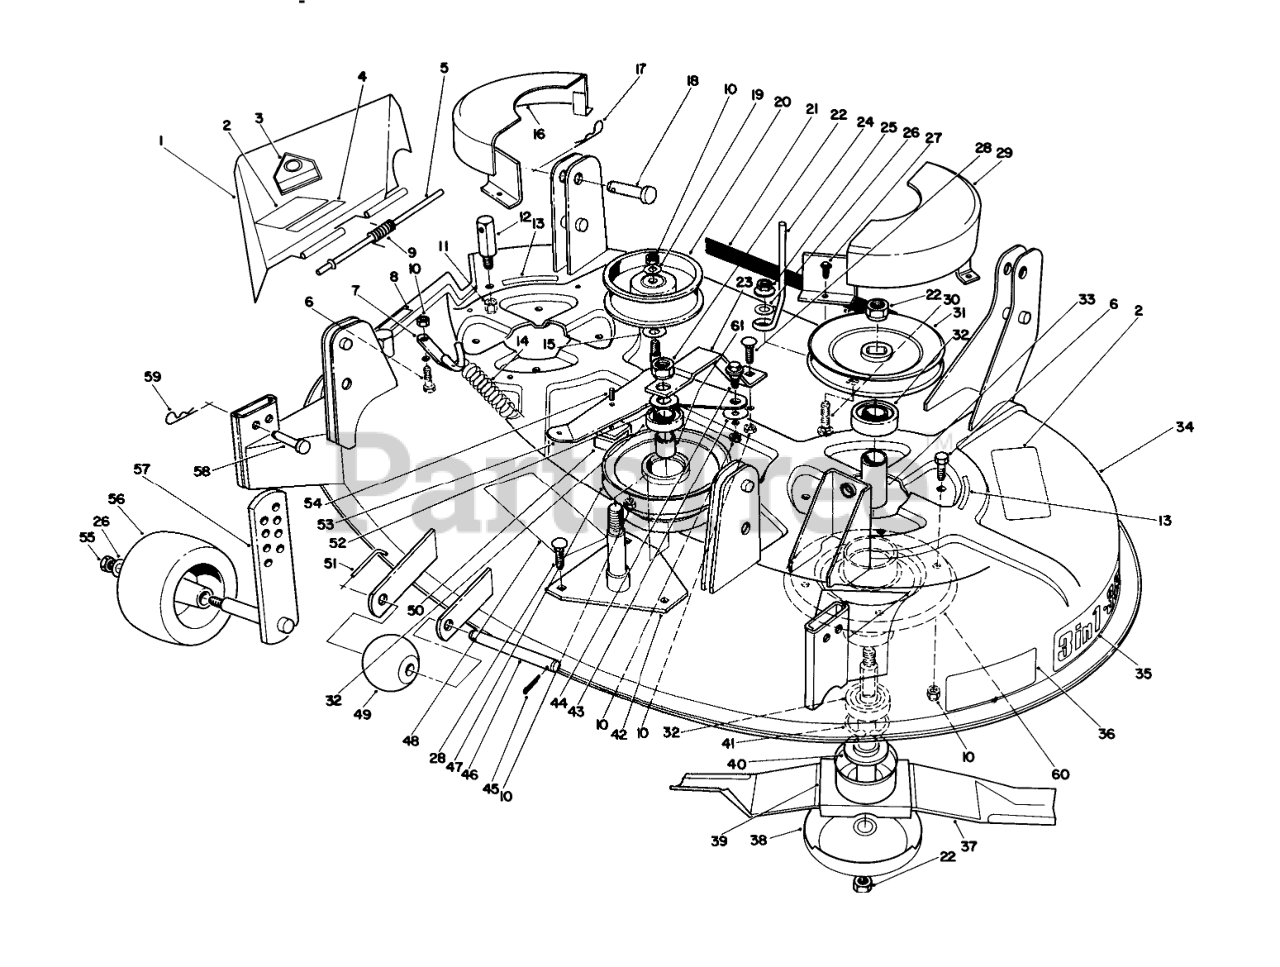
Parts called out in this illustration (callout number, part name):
1	Deflector Assembly (Incl. Ref. #2-4)
2	DECAL-DANGER, THROWN OBJECT
3	DECAL-DANGER
4	DECAL-NO STEP
5	ROD-HINGE DEFLECTOR
6	SCREW-HH
7	SPRING ROD
8	DECAL-DANGER, DEFLECTOR
9	SPRING
10	NUT-LOCK, NI
11	NUT-LOCK, NI
12	REAR PIVOT POST (PLTD)
13	DECAL-DANGER, SHIELD
14	DECK TENSION SPRNG O
15	WASHER-FLAT
16	RH BELT COVER WA B
17	PIN-HAIR
18	PIN-CLEVIS
19	WASHER-FLAT
20	PULLEY-IDLER
21	V-BELT
23	PULLEY SUPPORT B
24	BELT ROD
25	NUT-HF
26	WASHER-FLAT
27	SCREW-HWHTF
28	BOLT-CARR
29	Cover-Belt L.H.
30	SCREW-CARR
31	DECK PULLEY
32	BEARING-BALL
33	BEARING SPACER
34	Deck ) 38" (Incl. Ref. #8, 13, 35, 36 & 48)
35	DECK DECAL
36	DECAL - WHEEL ADJUSTMENT
37	Blade
38	Cup
39	SPINDLE SHAFT WA
40	IDLER SPACER
41	RING-RETAINING
42	JACK SHAFT WA B
43	WASHER-PIVOT
44	SCREW-SHOULDER
45	PIN-COTTER
46	SHAFT-ROLLER
47	PULLEY ASSEMBLY
48	BELT ROUTING DECAL
49	ROLLER
50	IDLER BRKT GUIDE
51	PIN-SPECIAL
52	WASHER-FLAT
53	IDLER BRACKET WA B
54	PIN-COIL
55	NUT-LOCK, NI
56	WHEEL-GAGE
57	GAGE-WHEEL
58	PIN-CLEVIS
59	PIN-HAIR
60	Spindle
61	BEARING SPACER
